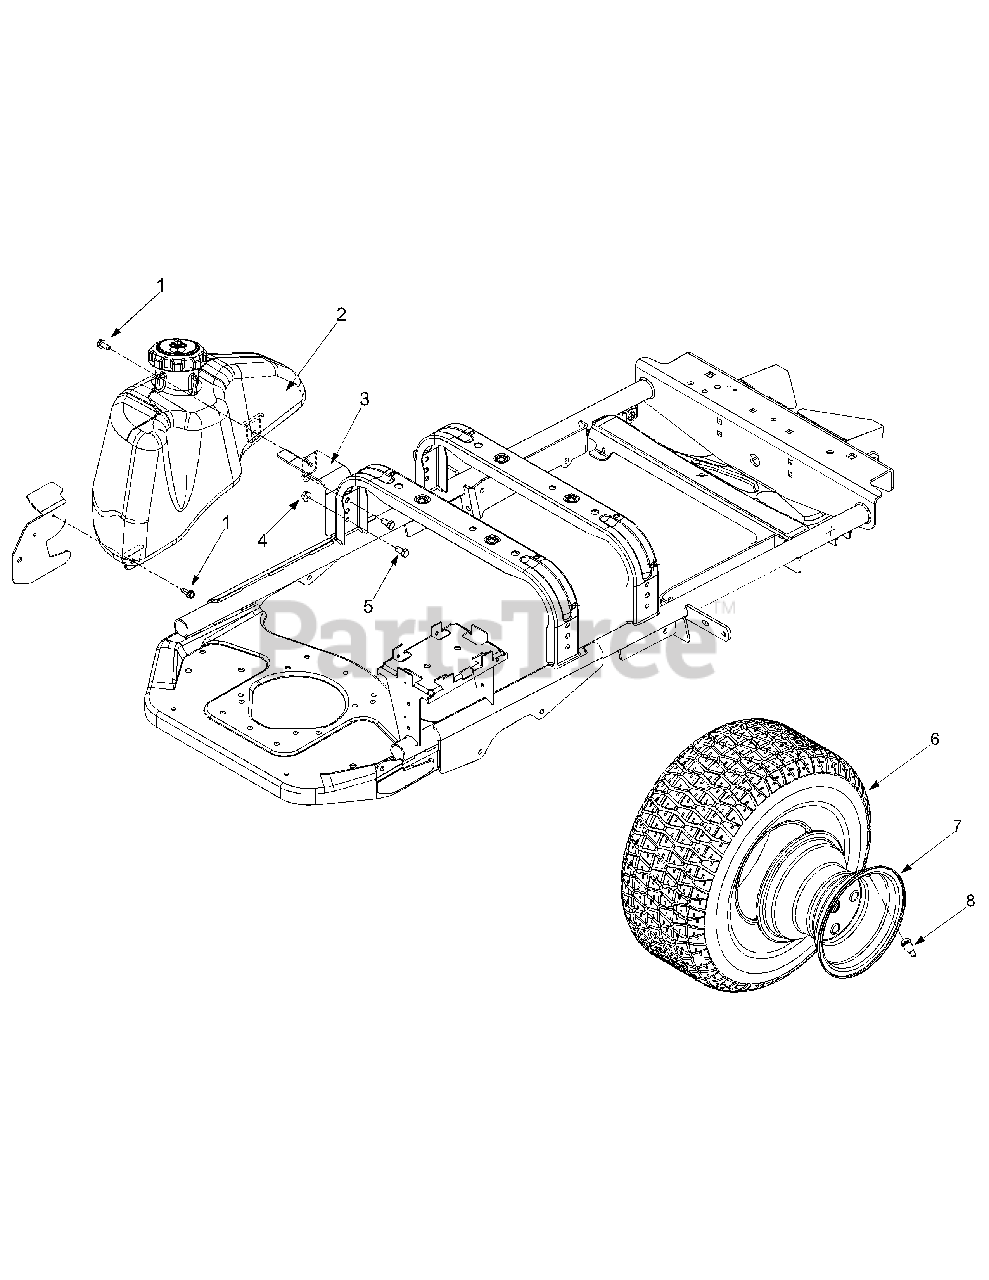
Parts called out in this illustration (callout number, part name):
1	Hex Washer Screw 5/16-18 x .75
2	Tank 4.0 Gal
5	Hex Cap Screw 3/8-16 x .75
6	Tire 20.0 x 7.0 x 8.0
